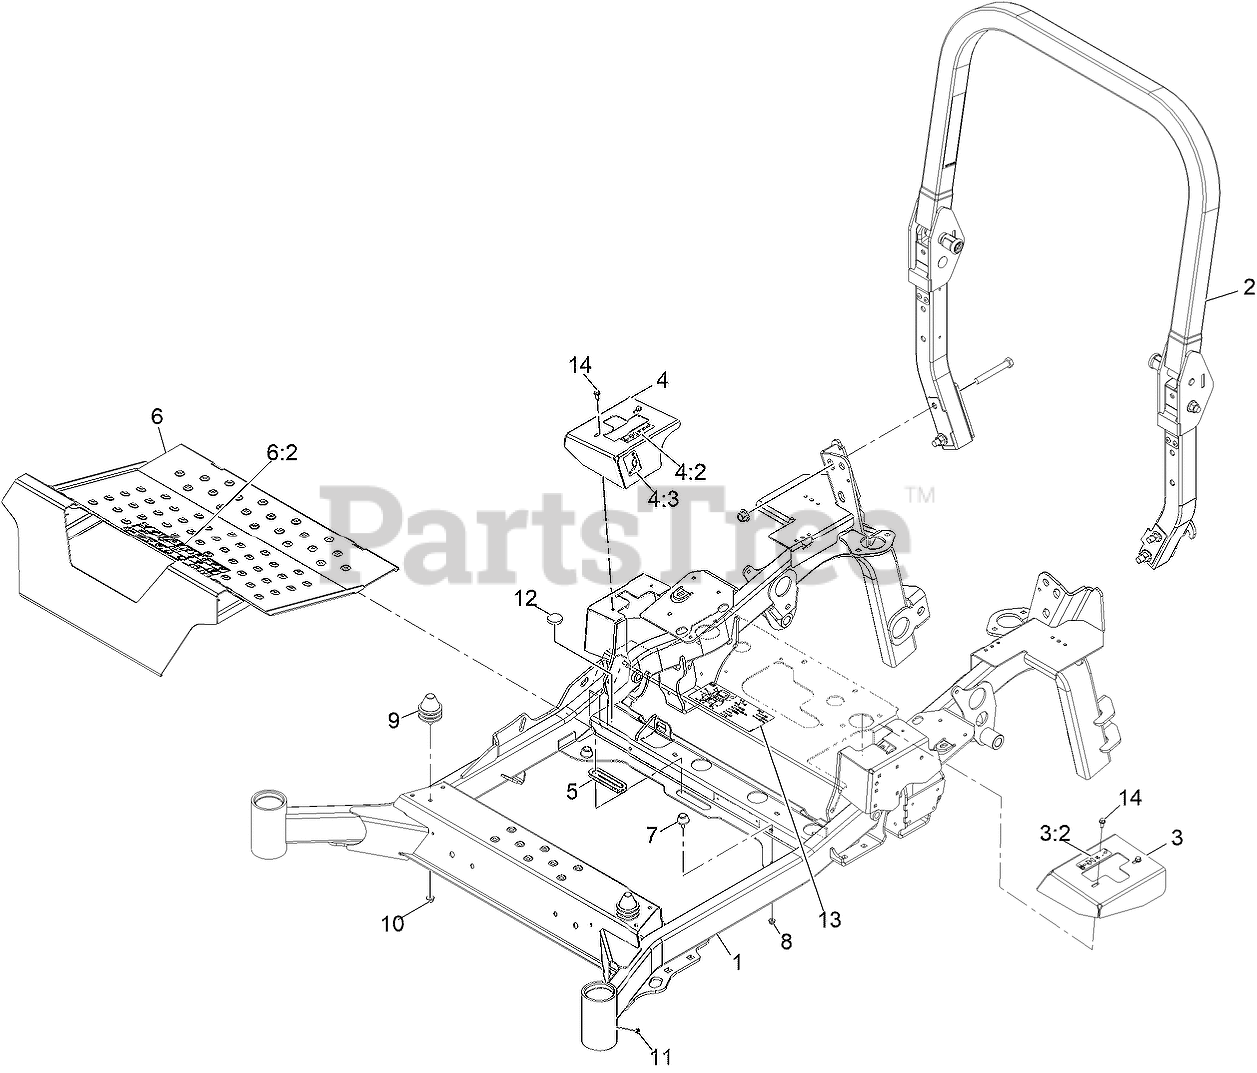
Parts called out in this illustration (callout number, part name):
2	ROPS ASM
3	COVER-MOTION CONTROL, LH
3:2	DECAL-CONTROL, MOTION
4	COVER-MOTION CONTROL, RH
4:2	DECAL-CONTROL, MOTION
4:3	DECAL-PARK BRAKE, CE
5	GROMMET-RUBBER
6	PAN-FLOOR
6:2	DECAL-DANGER
7	BUMPER-RUBBER
9	ISOLATOR
10	NUT-HF, NI
12	BUMPER-PUSH-IN, RUBBER
13	DECAL-SERVICE AID
14	SCREW-HWH
